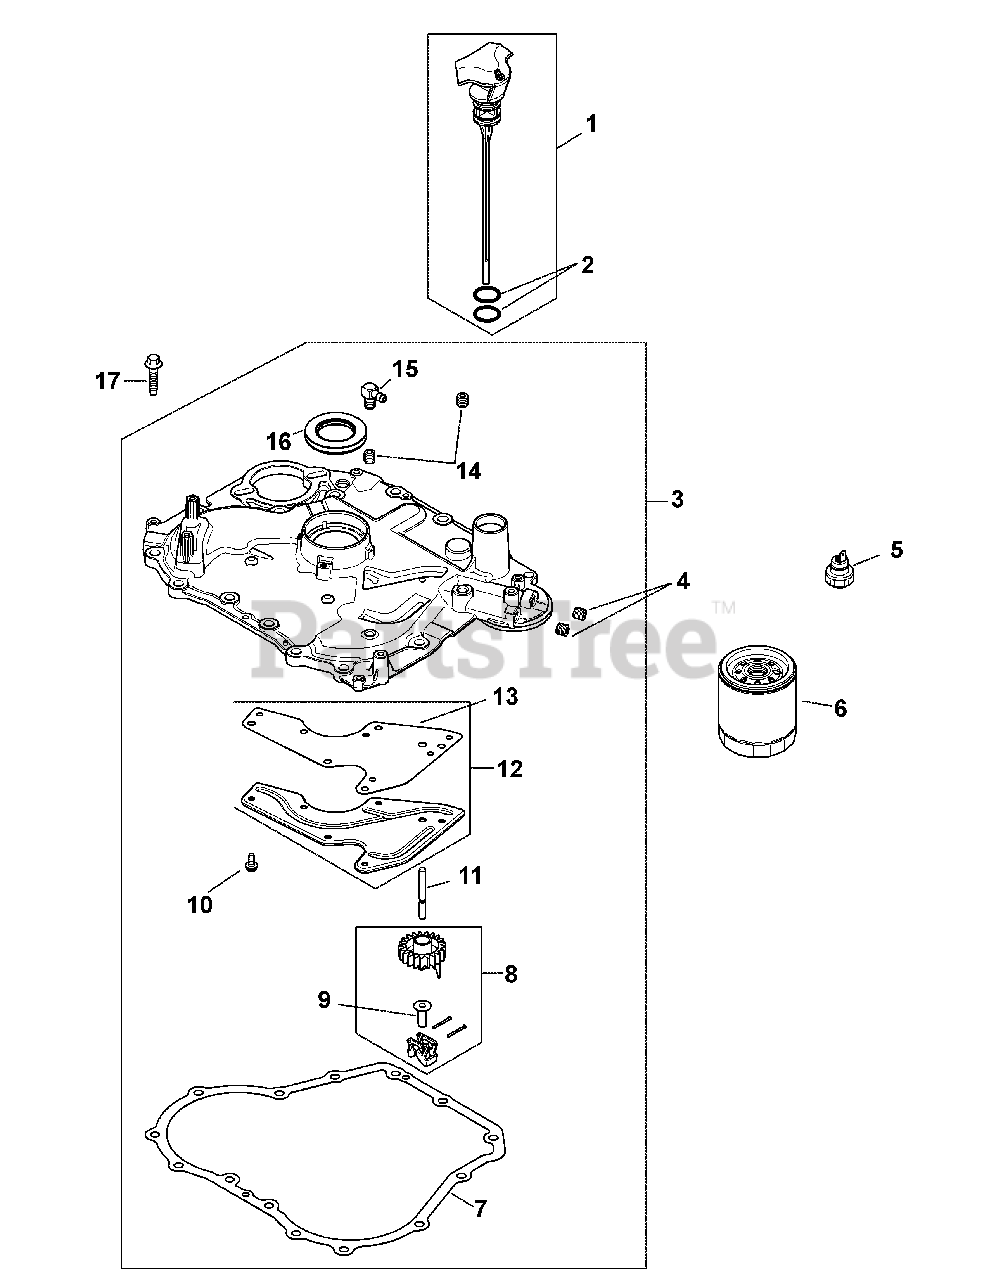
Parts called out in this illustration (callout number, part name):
1	Dipstick Assembly-Gold
2	O-Ring
3	Kit, Closure Plate Assembly
3	Closure Plate Assembly
4	Plug, Ctsk Pipe 1/8"
5	Switch, Oil Pressure
6	Filter, Oil
7	Gasket, Closure Plate
8	Governor Gear Assembly
9	Pin, Governor Regulating
10	Screw, Flg Thd Frm M5X0.8X13
11	Shaft, Governor Cross
12	Kit, Oil Passage Cover
13	Gasket, Oil Passage
14	Plug, Ctsk Pipe 1/8"
15	Connector, 90° Hose
16	Seal, Oil
17	Hex Flange Screw,1/2 Dog Point
